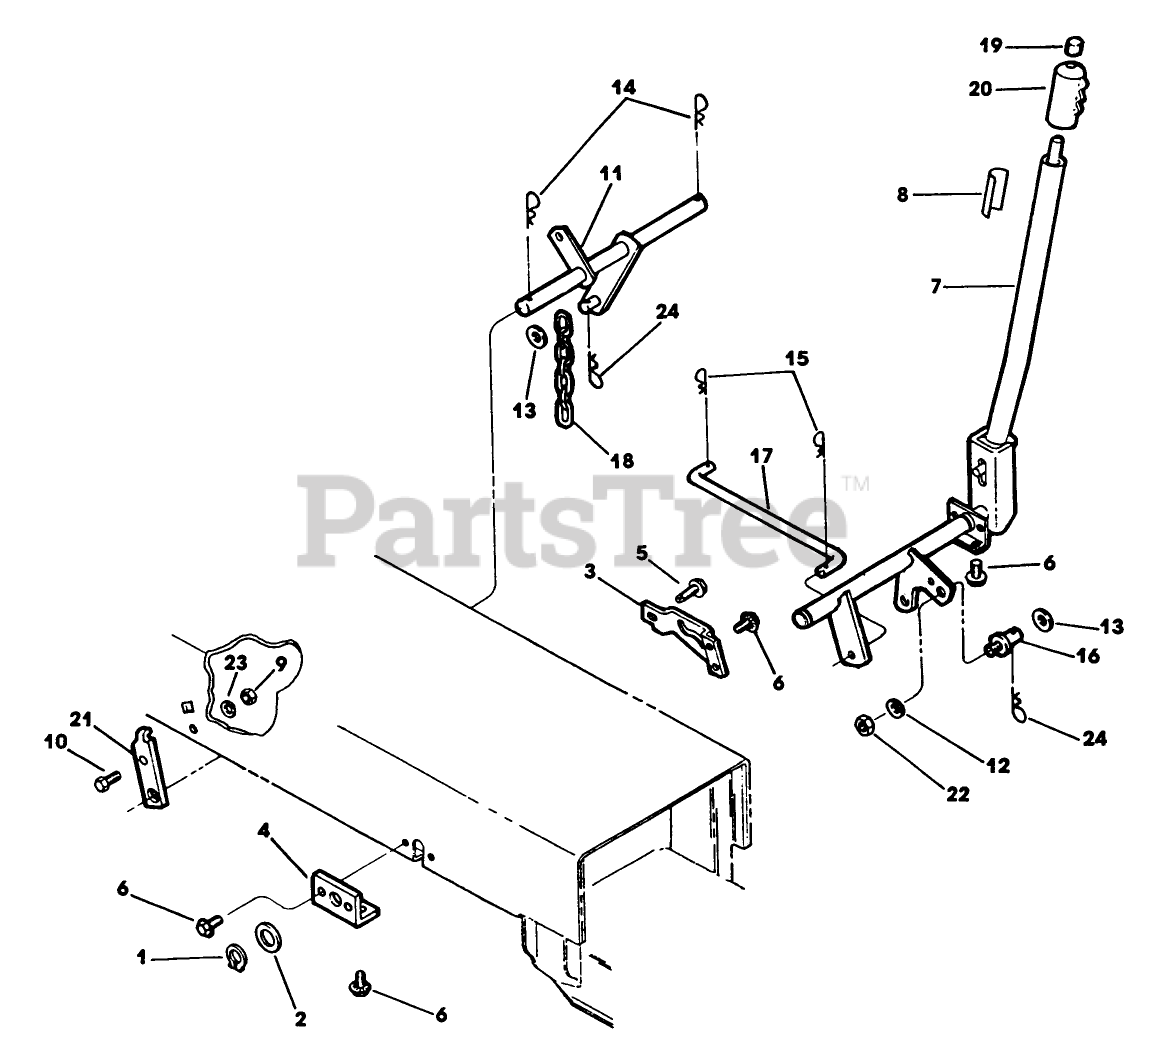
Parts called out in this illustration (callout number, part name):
1	RING-RETAINING
2	WASHER
8	STICKER-LIFT
9	NUT SS
11	LIFT ARM WELDMENT
12	WASHER
14	PIN - SPRING CLIP
15	PIN-HAIR
19	TIP-ROD
21	ARM-MOWER LIFT
22	NUT
24	PIN-HAIR
